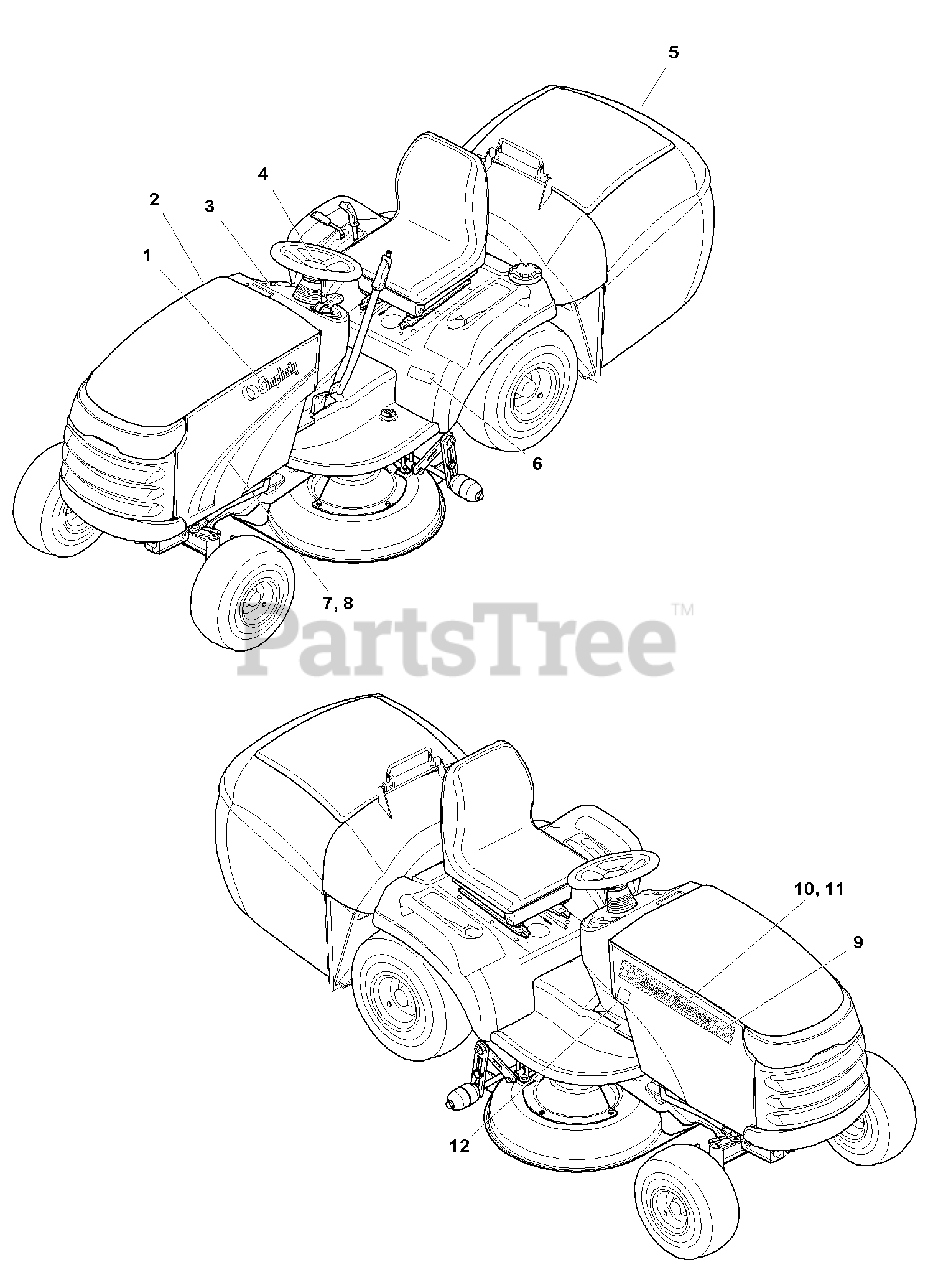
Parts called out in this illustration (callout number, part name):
1	DECAL, Simplicity, Silver & Blue
2	DECAL, Touch Up, Deep Orange
3	DECAL, Baron, 16HP Only
4	DECAL, Icon, Simplicity
5	DECAL, Simplicity
6	DECAL, Baron
7	DECAL, Simplicity, Hood Stripe, LH
8	DECAL, Simplicity, Hood Stripe, RH
9	DECAL, 2416H
9	DECAL, 2418H
10	DECAL, Massey Ferguson, Hood Stripe, LH
11	DECAL, Massey Ferguson, Hood Stripe, RH
12	DECALTouch Up, Massey Ferguson, Red
